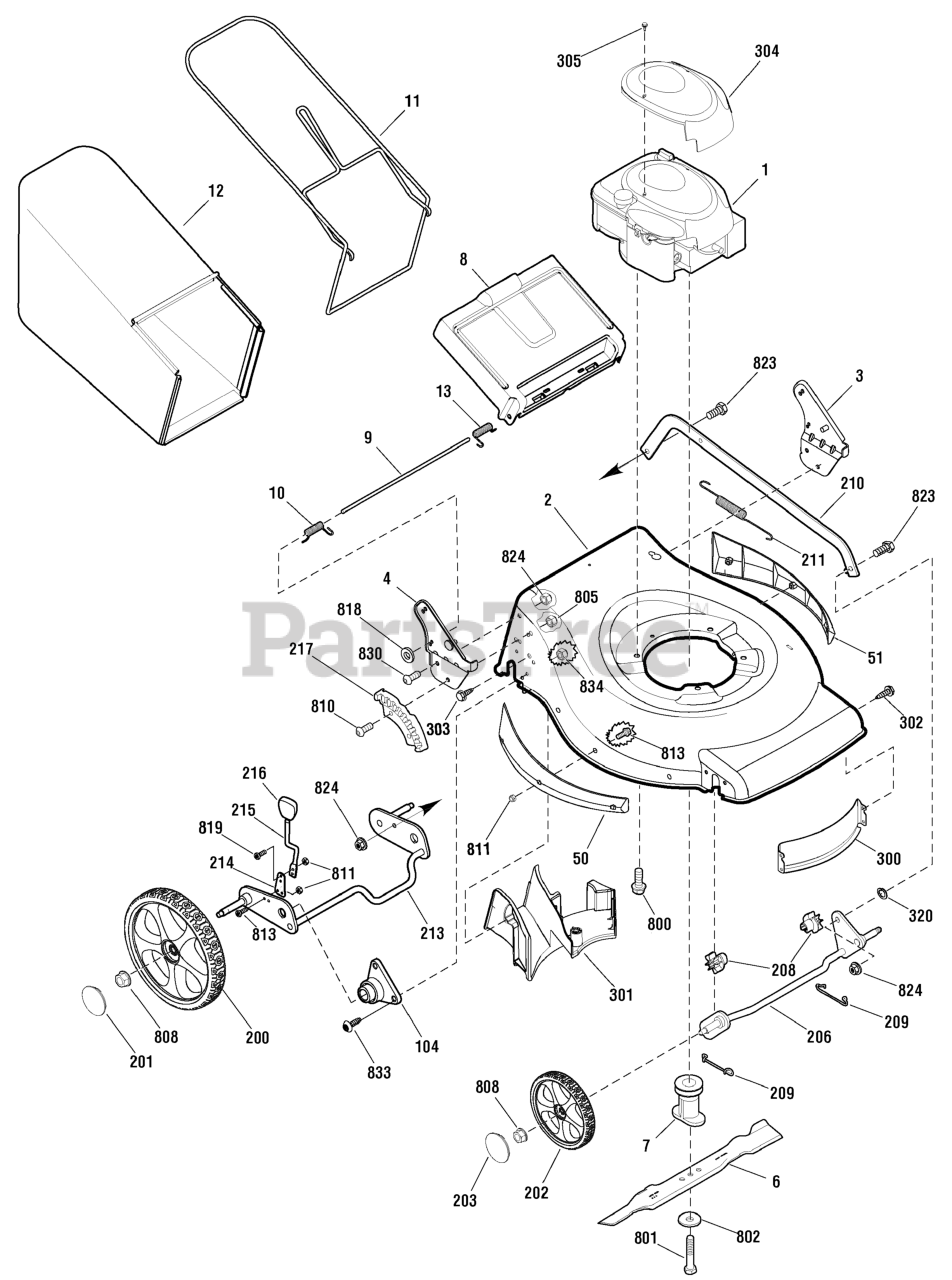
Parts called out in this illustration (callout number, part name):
1	* ENGINE
2	MOWER HOUSING
3	BRACKET ASSEMBLY, Left Handle
4	BRACKET ASSEMBLY, Right Handle
6	BLADE, 19 Inch
7	BLADE ADAPTER ASSEMBLY
8	DOOR, Rear
9	ROD, Rear Door
10	SPRING, Torsion Rear Door, Right
11	FRAME ASSEMBLY
12	BAG ASSEMBLY
13	SPRING, Torsion Rear Door, Left
50	SIDE GUARD, Right
51	SIDE GUARD, Left
104	SLEEVE ASSEMBLY, Rear Axle
200	WHEEL, Rear
201	HUBCAP, Rear
202	WHEEL, Front
203	HUBCAP, Front
206	CROSSBAR ASSEMBLY, Front
208	BUSHING, Front Crossbar
209	SPRING, Clip Crossbar
210	LINK, Single Lever, High Wheel
211	SPRING, Extension
213	REAR CROSSBAR
214	SPRING, Adjuster
215	LEVER, Height Adjustment
216	KNOB, Adjuster
217	BRACKET, Height Adjuster
300	BAFFLE, Front, 19
301	BAFFLE, Rear, 19
302	SCREW, Pan Head, Taptite, 1/4-20 x 1/2
303	SCREW, Pan Head, Taptite, 1/4-15 x 5/8
304	SHROUD, With Label
305	SCREW, Hex Washer Head
320	WASHER, Wave
800	SCREW, Hex Head, 3/8-16 x 1
801	BOLT, Blade, 3/8-24 x 2
802	WASHER, Belleville
805	NUT, Nylock, M8 x 1-1/4
808	NUT, Flange, 3/8-16
810	BOLT, Hex Key Head
811	NUT, Nylock
813	SCREW, Torx Head, M5 x .8 x 14mm
818	PUSHNUT, 1/4
819	SCREW, Torx Head, M5 x .8 x 12.5mm
823	BOLT, Shoulder, 5/16-18 x 1
824	Nut, Flange, 5/16-18
830	SCREW , 5/16-18 x 3/4
833	SCREW, Torx, 1/4-20 x 5/8
834	NUT, Flange Lock, 1/4-20
1000	DECAL KIT
